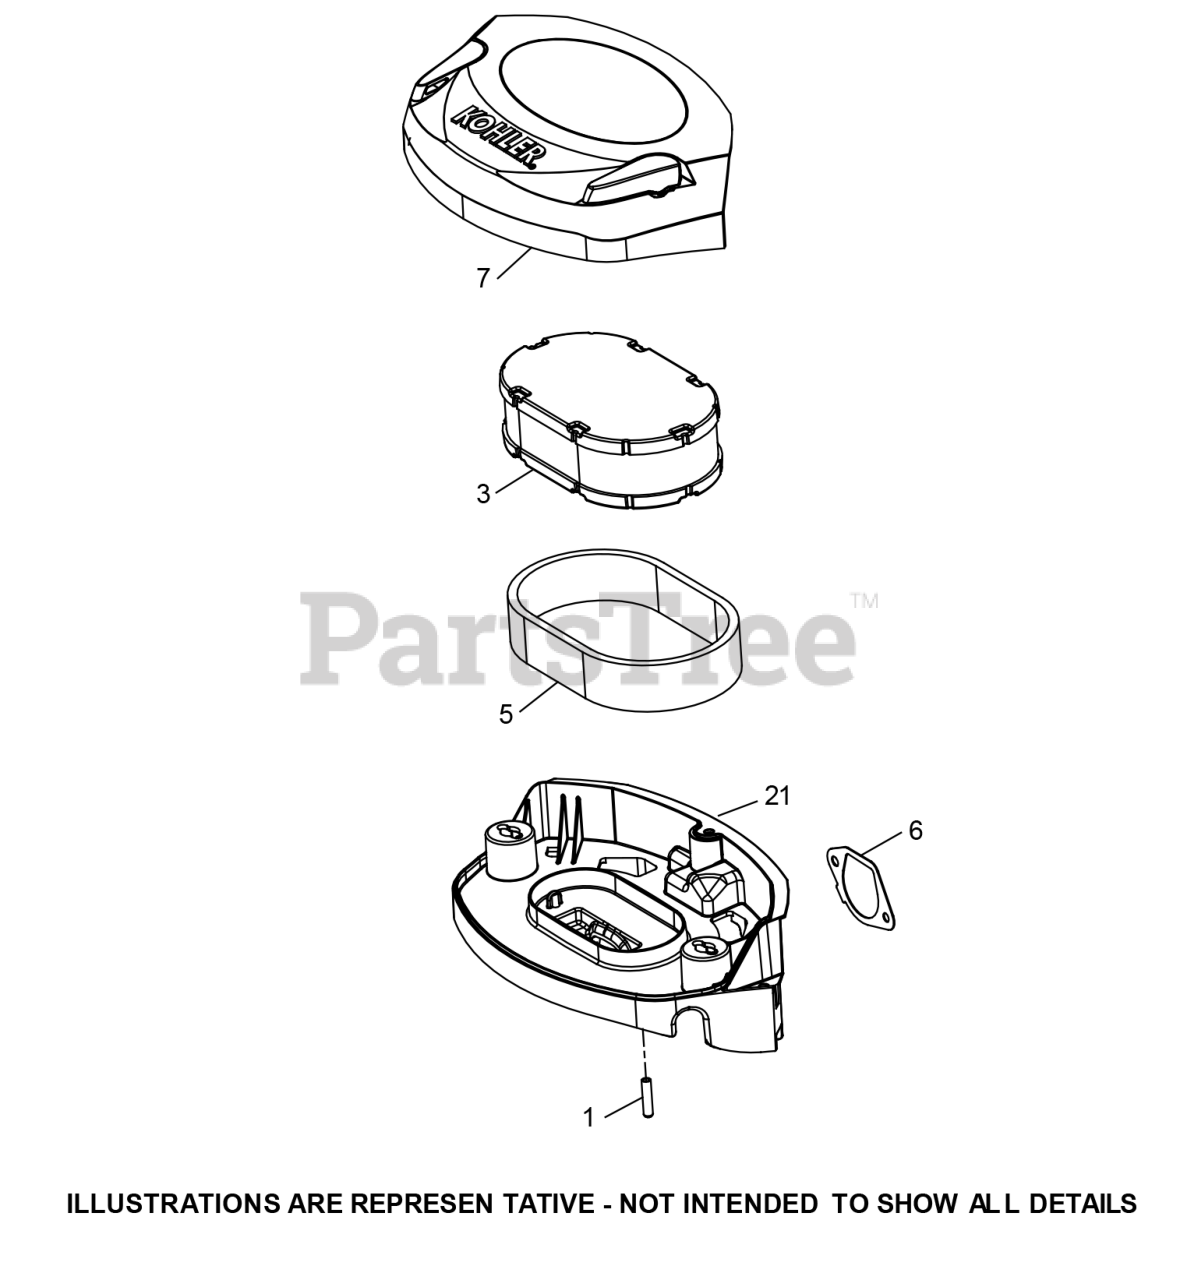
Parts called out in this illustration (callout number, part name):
3	FLTR KIT-AIR/PRECL
5	PRECLNR-FOAM (LPAC
6	GASKET-AIR CLNR BA
7	AIR CLEANER COVER ASSEMBLY
21	AIR CLEANER BASE ASSEMBLY
